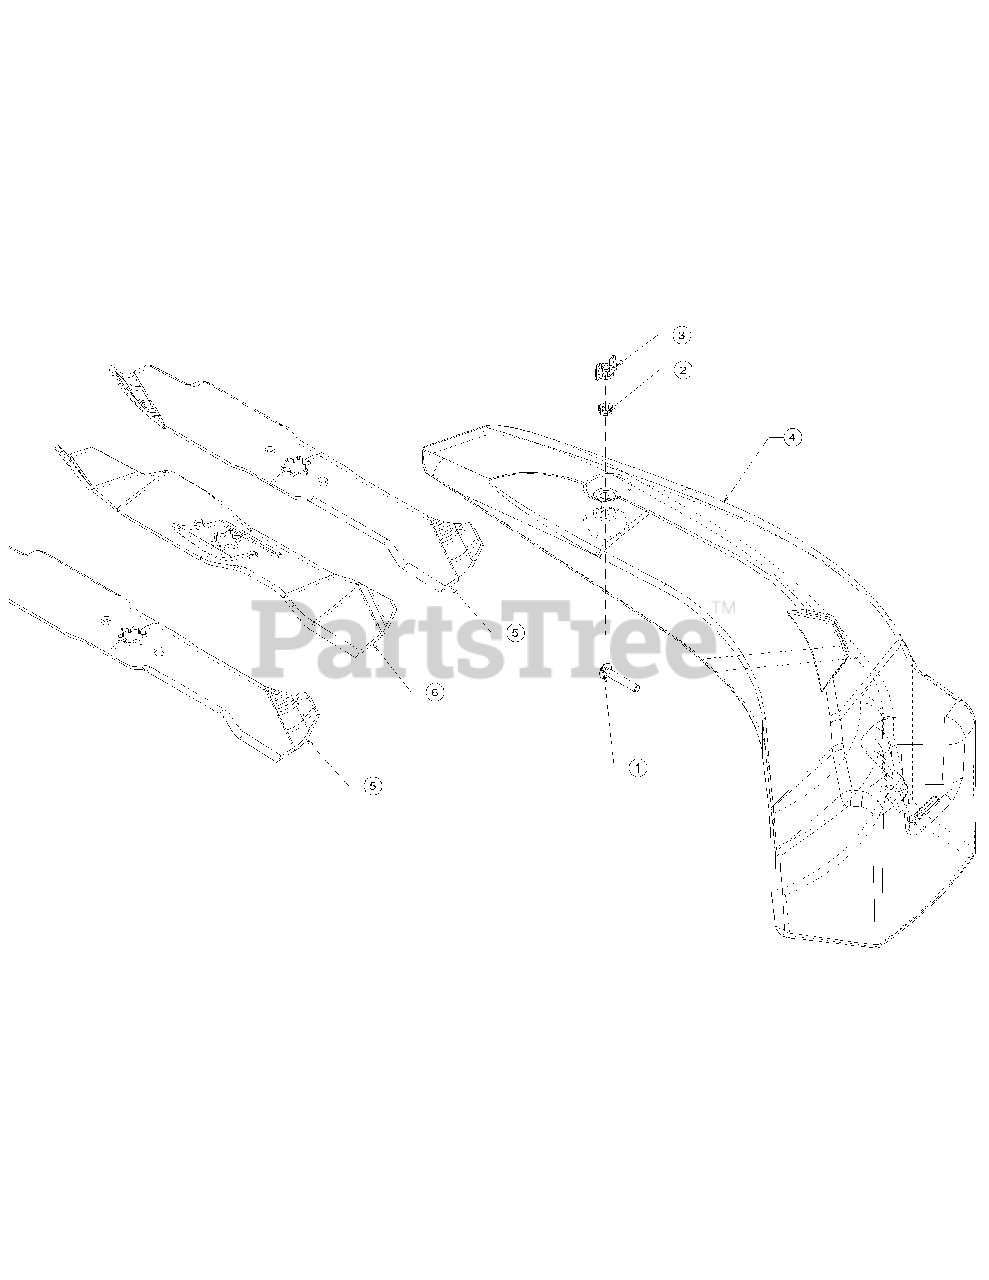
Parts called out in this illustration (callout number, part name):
1	Machine Screw (1/4")
2	Hex Locking Nut (1/4")
3	Plastic Wing Nut, 1/4"
4	Mulch Plug
5	Two 16.28" Mulching Blades
6	One 14.88" Mulching Blade
